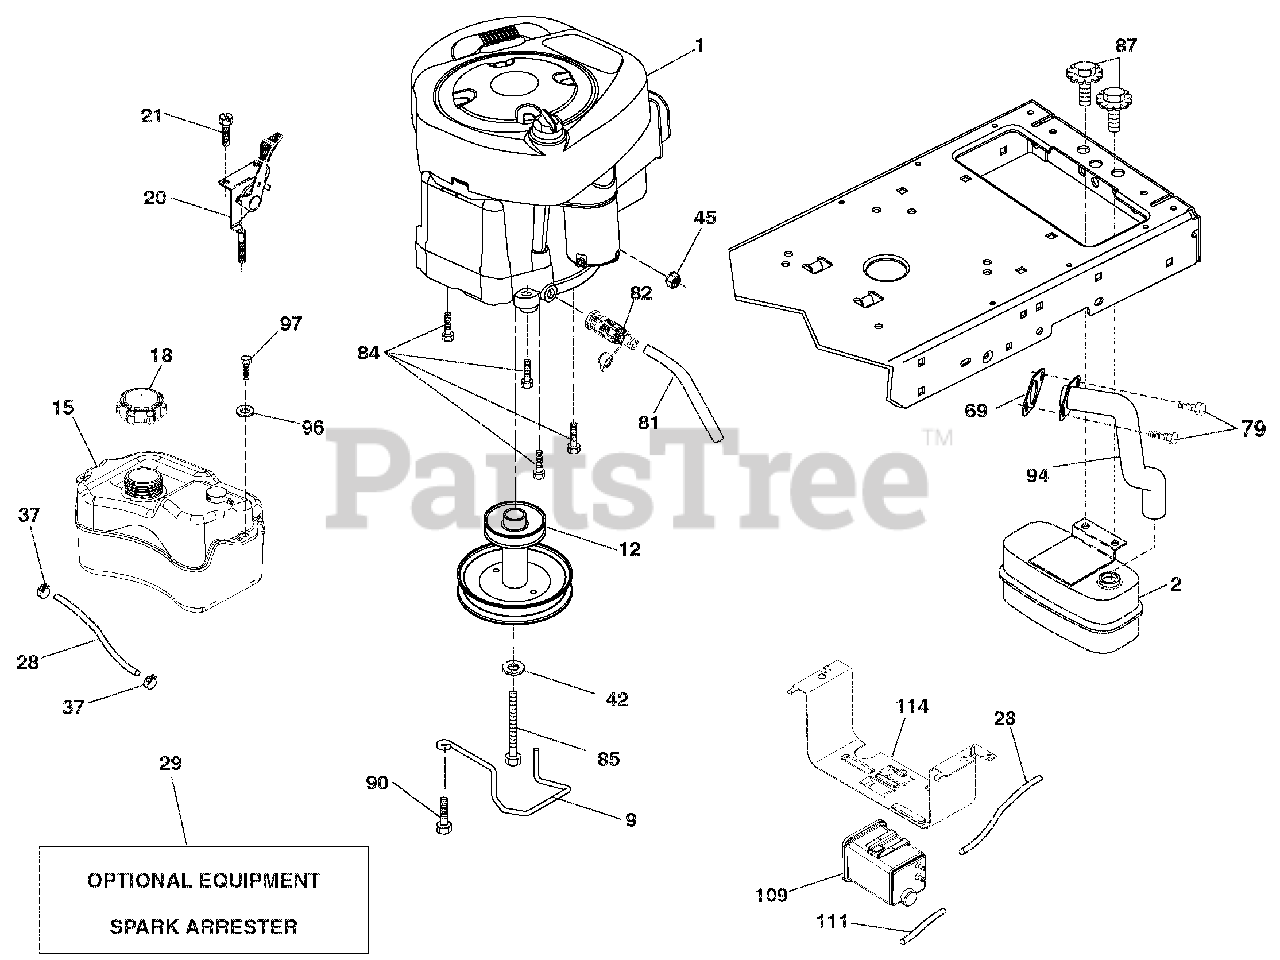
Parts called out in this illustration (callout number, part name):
1	ENGINE B&S MODEL NO. 33R877-0010-G1(586071001)(ORDER PARTS FROM ENGINE MANUFACTURER.)
2	MUFFLER
9	KEEPER.BELT.ENGINE.3.25"NSTL
12	ENGINE PULLEY
15	TANK ASM.FUEL.1.50.CARB.CA.SVC
18	CAP FUEL
20	CONTROL THROTTLE/CHOKE
28	LINE.FUEL.22"FRONT.EMIS.CA.LP
29	KIT.SPARK ARRESTOR(392390 B&S)
37	CLAMP.HOSE.BLK.
42	WASHER.LOCK.HVY HLCL.SPR.7/16
45	Nut, Keps Hex 1/4-20 unc
69	Gasket Eng 1 313 Id Tin Plated
79	SCREW.SOCKET HD.5/16-18 X .75
81	TUBE.DRAIN.OIL.EASY
82	VALVE OIL DRAIN
84	Screw 3/8-16 x <
85	BOLT.HEX.7/16-20X4XGR5-1.5THR.
87	BOLT.5/16-18UNCX3/4 W/SEMS.BLK
90	SCREW.3/8-16X1.SMGML.TAP/R.BLK
94	EXHAUST TUBE
96	WASHER.9/32 X 7/8 X 16GA.
97	SCREW.HEXWSH.THDROL.1/4-20X3/4
109	CANISTER.CARBON.FILTER ASM.TEX
111	PURGE.LINE.CARB
114	CRADLE.CANISTER.CARBON
